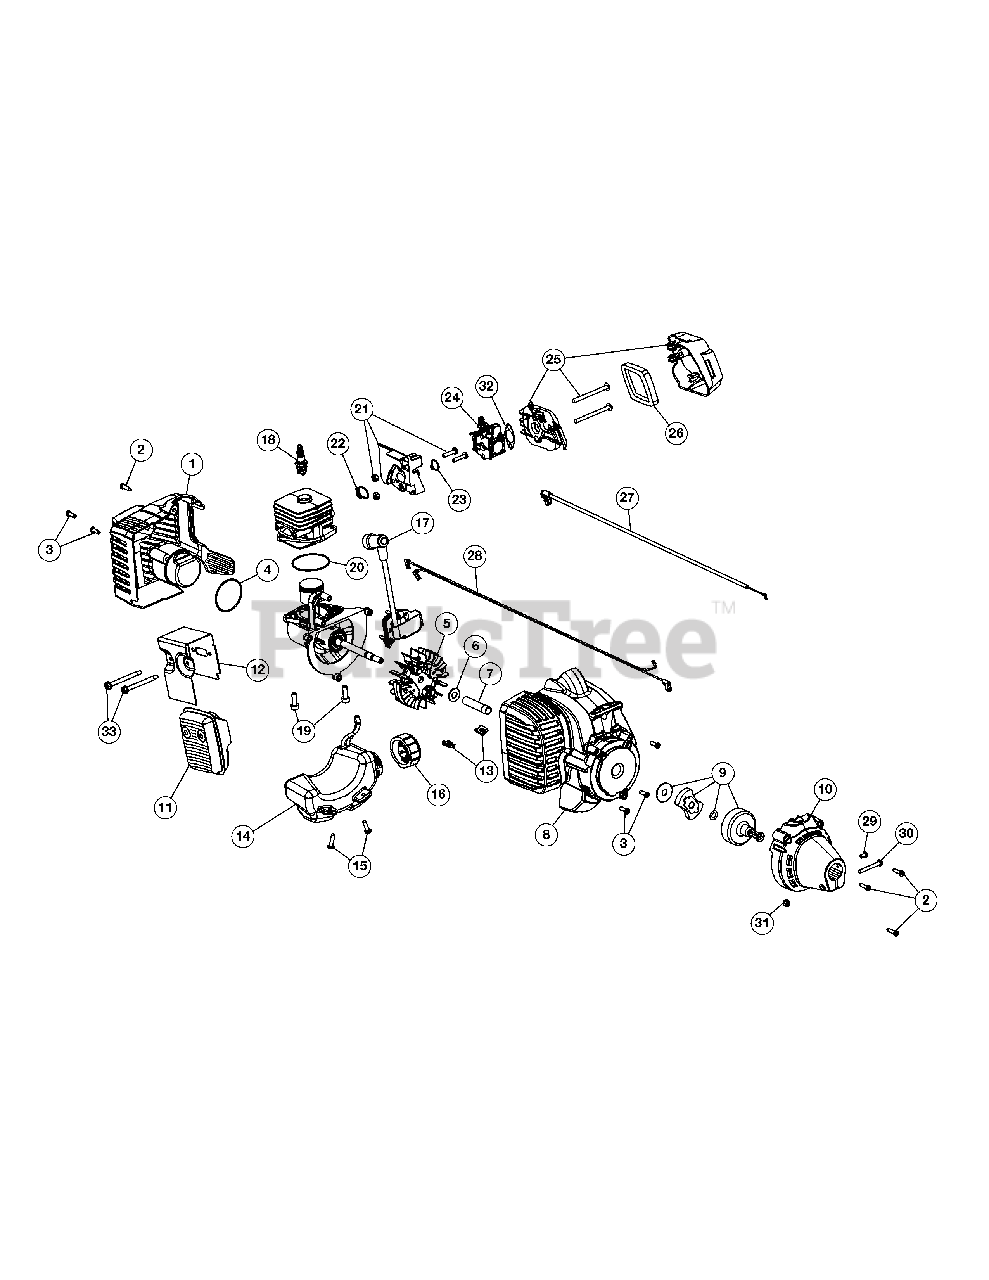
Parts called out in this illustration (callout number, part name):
1	Rear Cover Assembly (Incl. 2 & 3)
2	Cover Screw
3	Housing Screw
4	O-Ring
5	Flywheel Assembly
6	Washer
7	Spacer
8	Starter Housing (Incl. 3 & 13)
9	Clutch Assembly
10	Clutch Cover (Incl. 2)
11	Muffler Assembly (Incl. 12 & 33)
12	Muffler Gasket
13	U-shaped Nut
14	Fuel Tank Assembly (Incl. 15 & 16)
15	Tank Screw
16	Fuel Cap
17	Module Assembly
18	Spark Plug
19	Crankcase Bolt
20	Crankcase O-Ring
21	Insulator Assembly (Incl. 22 & 23)
22	Insulator O-Ring
23	Carburetor O-Ring
24	Carburetor
25	Air Cleaner Cover Assembly (Incl. 26)
26	Air Cleaner Filter
27	Throttle Cable
28	Lead Wires
29	Anti-rotation Screw
30	Clamp Screw
31	Clamp Nut
32	Air Cleaner Gasket
33	Muffler Screw
